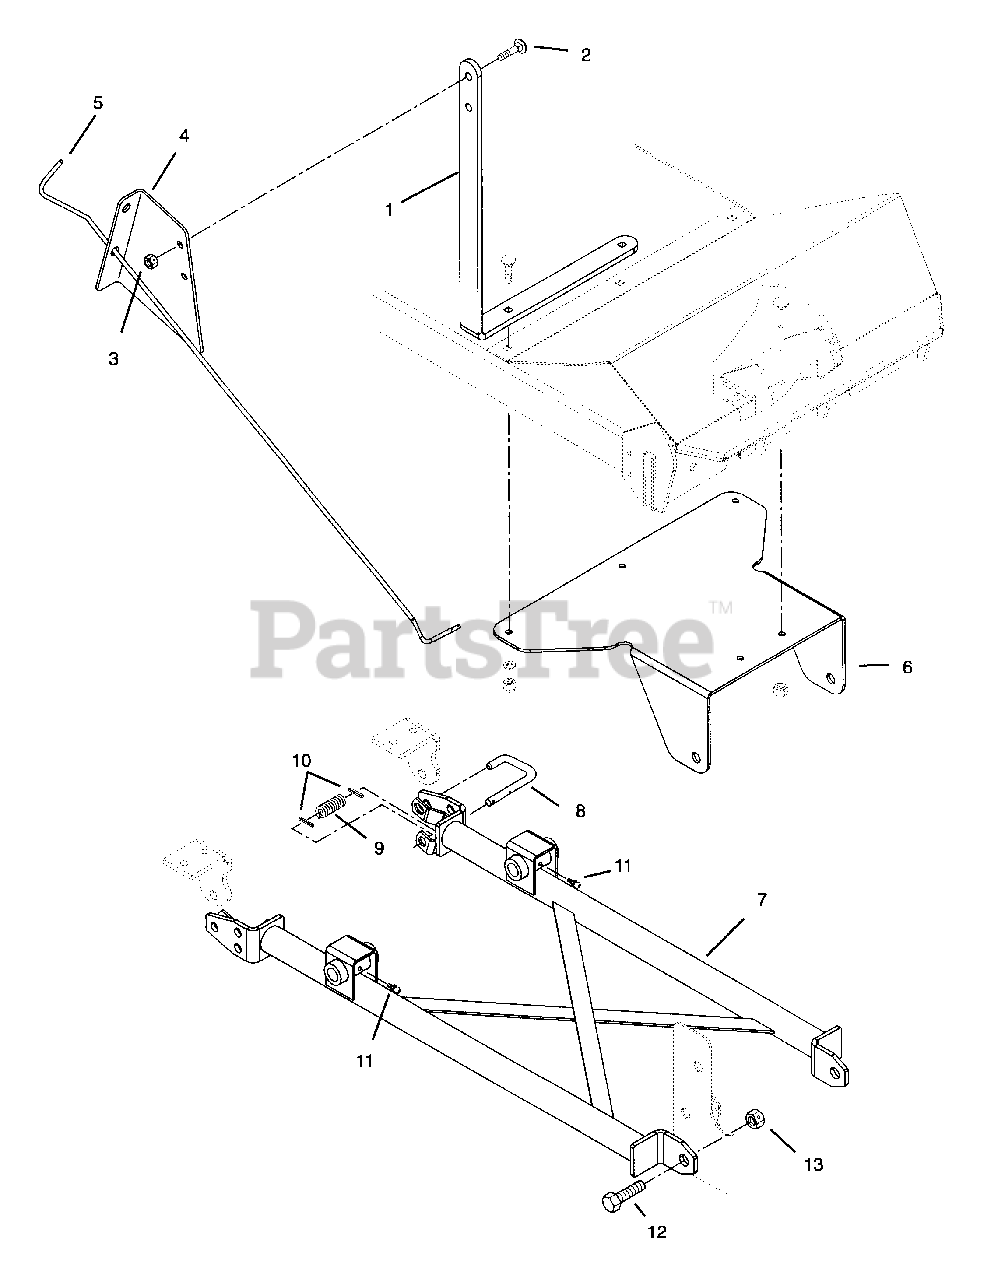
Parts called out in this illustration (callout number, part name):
1	CONTROL SUPPORT
2	BLT-RDHDSQNK .38-16X.75 SHT PL
3	@NUT-LK-CTR .38-16 YWZC
4	CONTROL BRACKET
5	ROD, CONTROL
6	HANGER BRACKET
7	SUPPORT WELDMENT
8	LATCH PIN
9	SPRG, COMP .058X.65X2.13 WLD15
10	PIN-ROLL .125X.75
11	FTG-LUBE .25-28X.256 YWZC
12	@BLT-HEX .62-11X1.50 GR5 YWZC
13	@NUT-LK-CTR .62-11 YWZC
